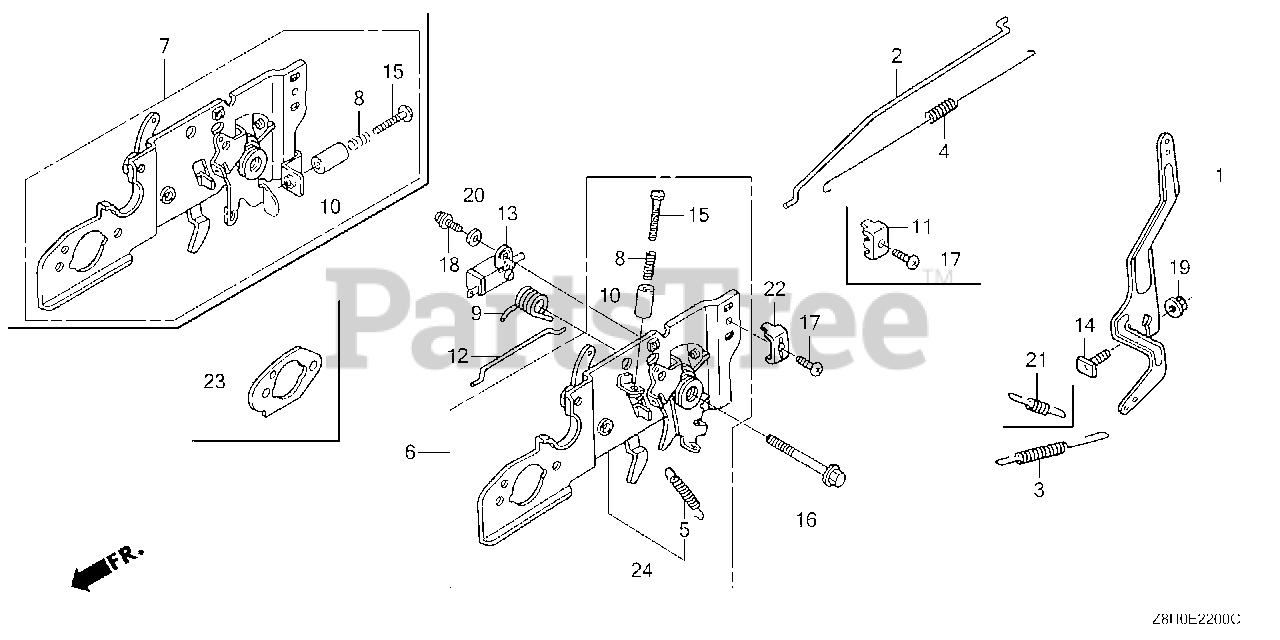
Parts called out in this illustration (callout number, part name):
1	ARM, GOVERNOR
2	ROD, GOVERNOR
3	SPRING, GOVERNOR
4	SPRING, THROTTLE RETURN
5	SPRING, LEVER
6	BASE, CONTROL
12	ROD, CHOKE
14	BOLT, GOVERNOR ARM
16	BOLT, FLANGE (6X45) (CT200)
17	SCREW, PAN (5X16)
19	NUT, FLANGE (6MM)
22	HOLDER, CABLE
